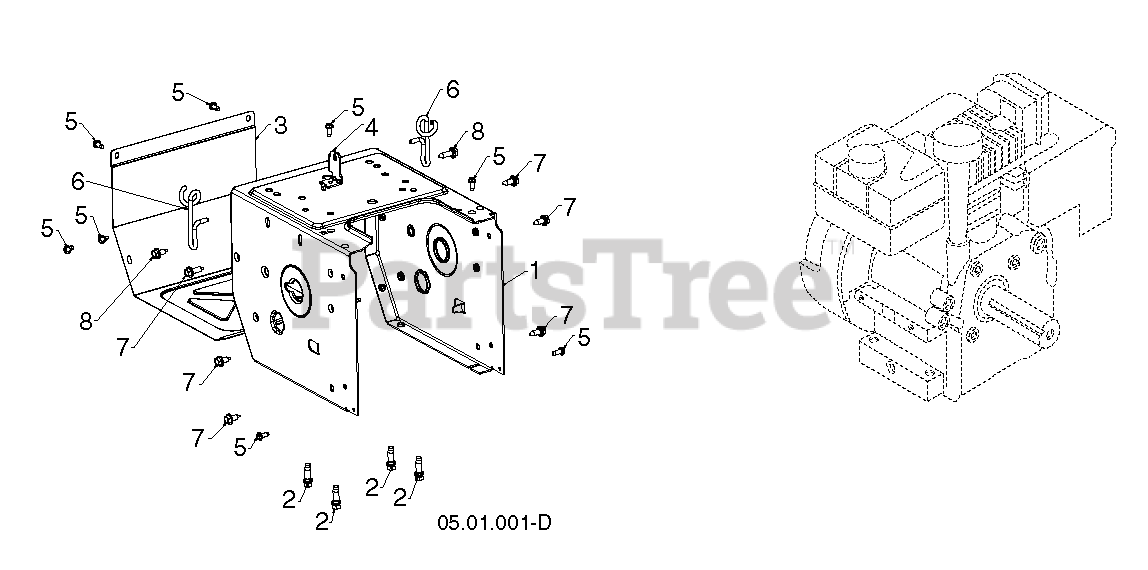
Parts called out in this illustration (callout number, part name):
1	FRAME.GEAR.CASE.ORANGE
2	BOLT 3/8-16X1-1/8
3	COVER COVER.FRAME MS668 ORANGE
4	BRACKET.SHIFTER.SNOW.BLACK
5	SCREW 14-20 X 5/8
6	RP.SUPPORT CABLES WIREFORM
7	BOLT.HEX.HD.WASHER.5/16-18X.75
8	SCREW HEX_SERR_HD_5_16-18X1.0
